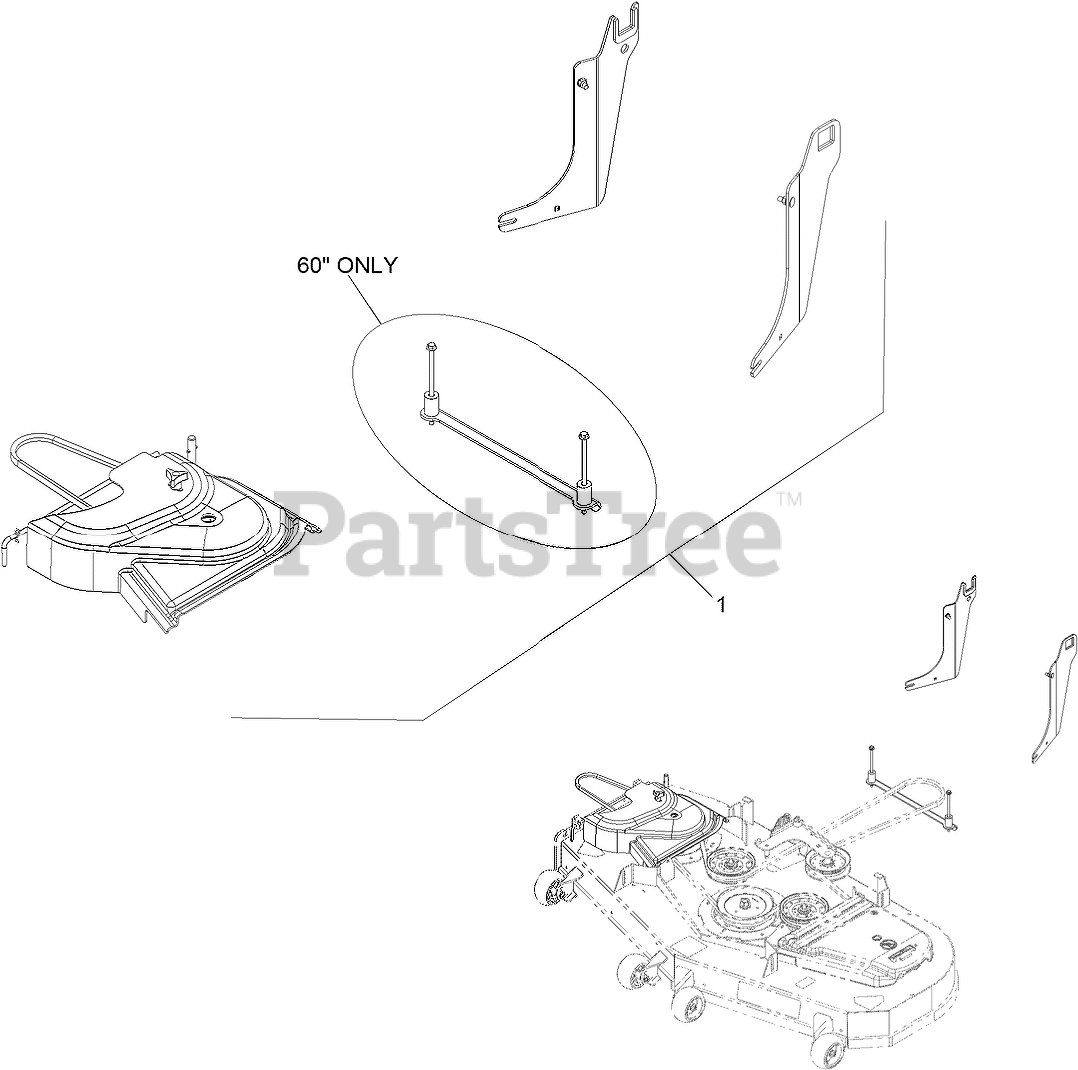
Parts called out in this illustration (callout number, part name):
1	Kit-Completing Qsp 44 Uve
1	Kit-Completing Qsp 48 Uve
1	Kit-Completing Qsp 52 Uve
1	Kit-Completing Pi 44 Uve
1	Kit-Completing Pi 48 Uve
1	Kit-Completing Pi 52 Uve
1	Kit-Completing Pn60 Uve
